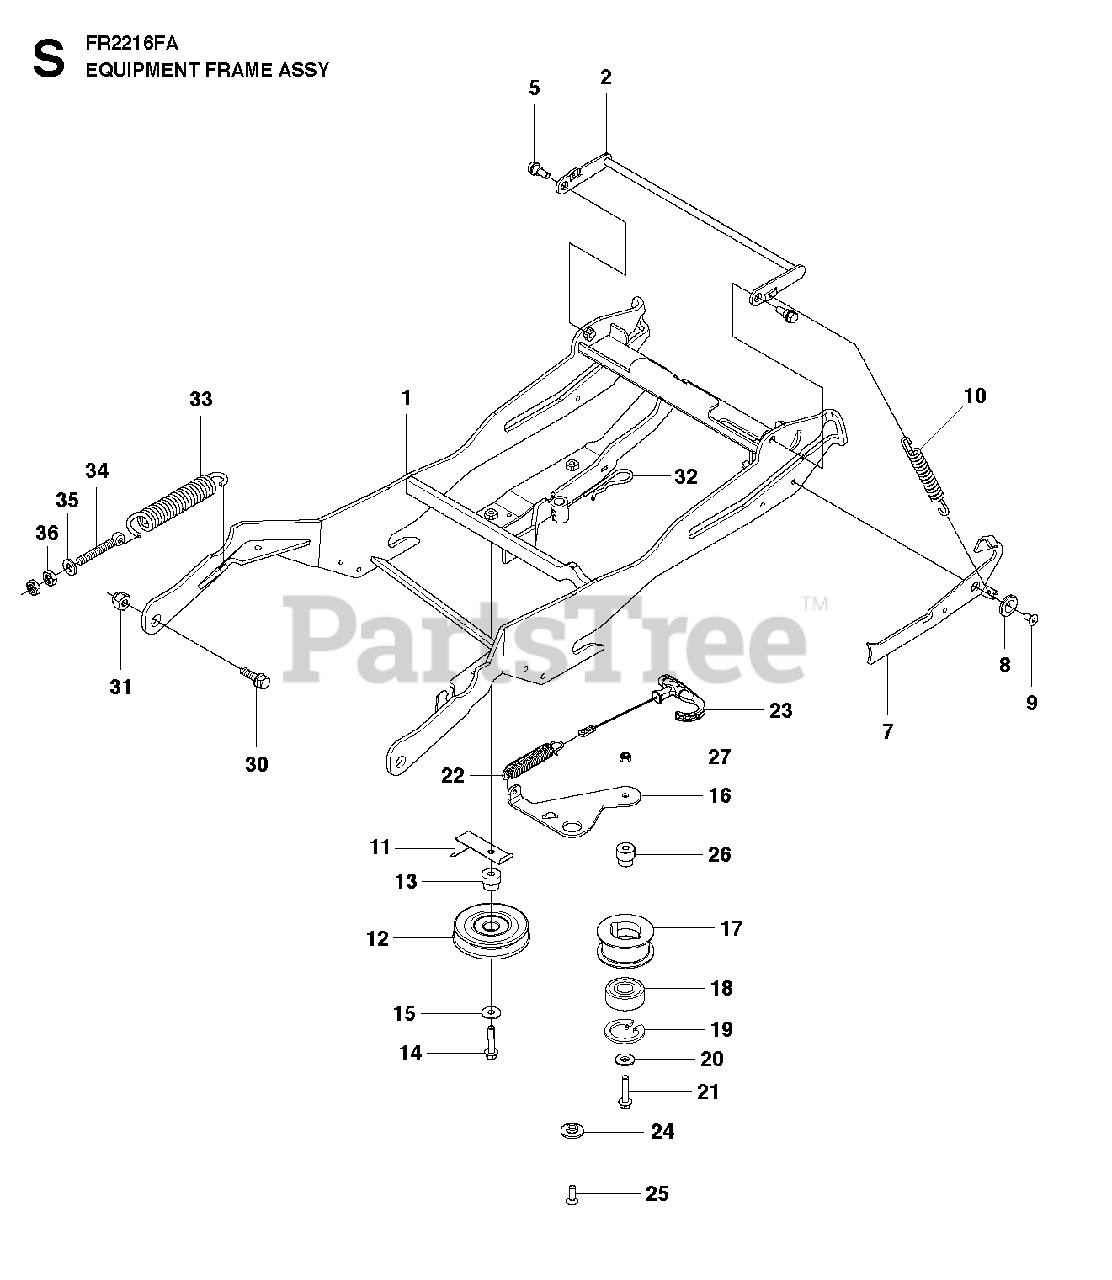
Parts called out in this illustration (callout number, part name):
9	SCREW IHCSFM
11	BELT GUIDE
17	%PULLEY
18	BALL BEARING 6004-2RS1
19	RETAINING RING
23	HANDLE ASSY
24	WASHER
27	LOCKNUT M8
35	WASHER
